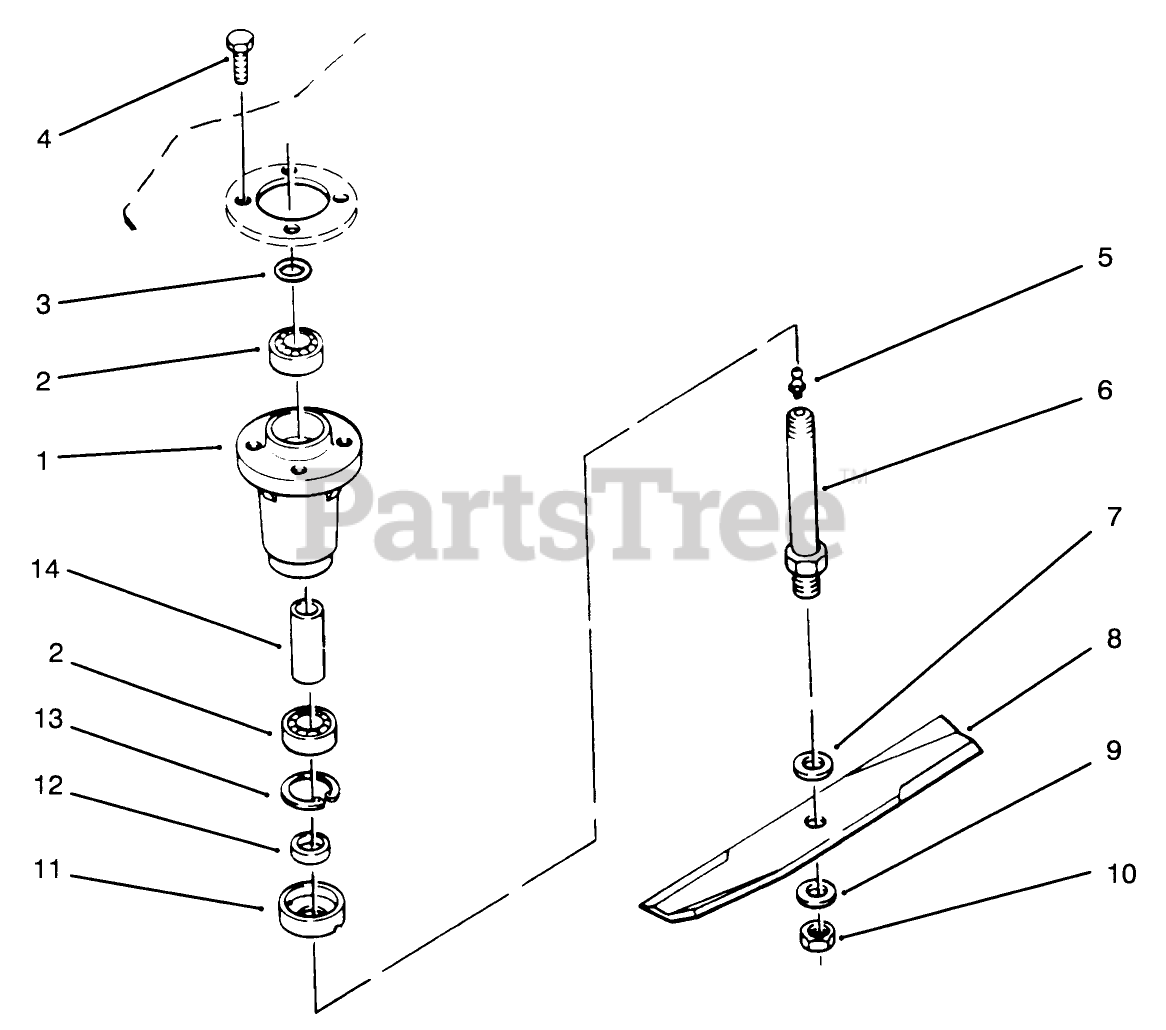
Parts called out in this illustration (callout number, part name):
1	HOUSING-SPINDLE
2	BEARING-BALL
3	O RING
4	SCREW-HH
5	FITTING-GREASE
6	SHAFT-SPINDLE
7	Washer
8	BLADE KIT
9	WASHER-FLAT
10	NUT-JAM
11	CUP-SPINDLE
12	SPACER-BLADE
13	RING-RETAINING
